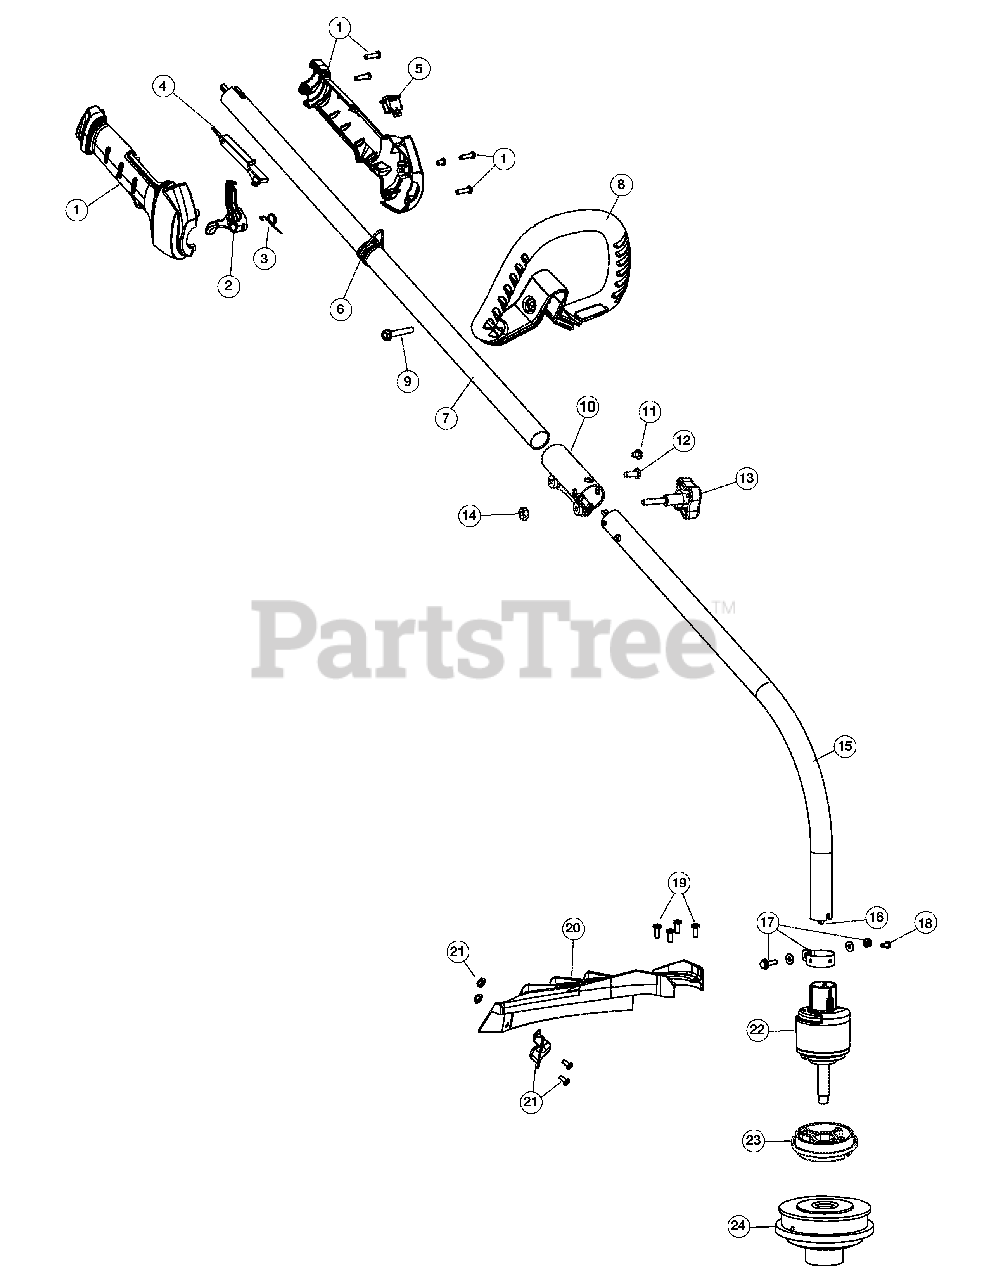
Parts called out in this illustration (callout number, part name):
1	Throttle Housing Assembly (includes 2-5)
2	Throttle Trigger
4	Throttle Lock-Out
6	Shoulder Strap Clip
7	Upper Driver Shaft Housing Assembly
8	D-Handle Assembly (includes 9)
10	Split Boom Coupler (includes 11-14)
11	Anti-Rotation Screw
13	Adjustment Knob
14	Knob Retaining Nut
15	Lower Drive Shaft Assembly (includes 16)
16	Flexible Drive Shaft
17	Lower Clamp Assembly (includes 18)
18	Anti-Rotation Screw
19	Shield Mounting Screw
20	Shield Assembly (includes 21)
21	Blade Assembly
23	Gearbox Spacer
24	Cutting Head Assembly
